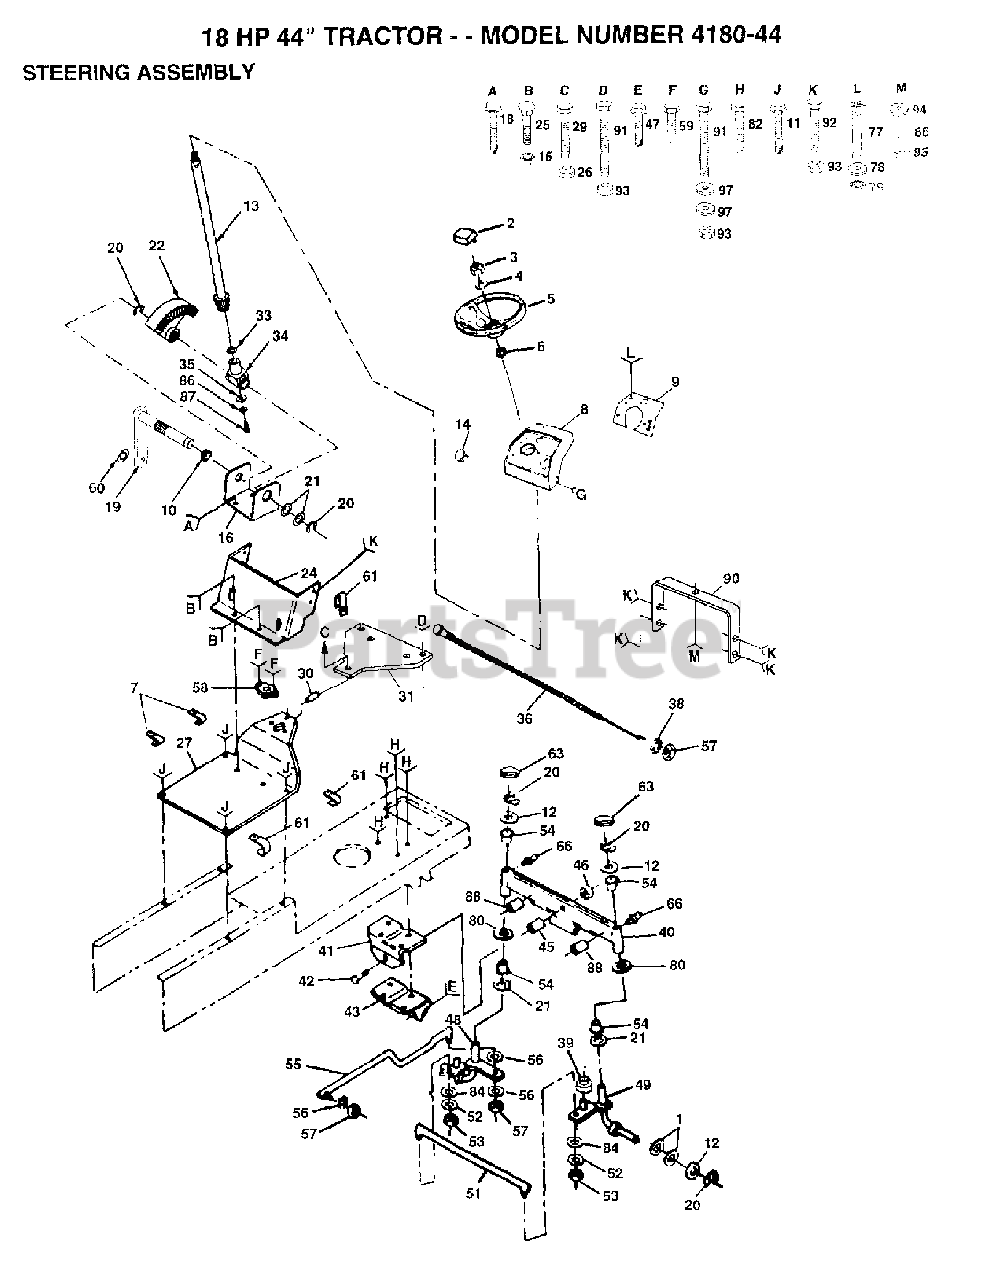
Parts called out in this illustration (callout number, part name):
2	INSERT STR WHL
3	NUT.HEX.1/2-20
5	Steering Wheel
7	CLIP,INSULATOR
10	NYLINER T (7283A)
14	PLUG-DASH T
16	BRKT,STEERING
19	SHAFT,PITMAN
20	RING CLIP
21	WASHER THRUST
22	GEAR.SECTOR
24	DASH LOWER YT NLA
26	NUT.71038.31-18.HEX.NYLOCK
31	PLATE, BATTERY
33	THRUST WASHER
34	SHAFT,SUPPORT
35	WASHER
36	CONTROL CHOKE
38	LOCKWASHER
39	Poulan TBD
40	AXLE ASSY
41	SUPPORT-SADDLE LT NLA
43	SUP-SADDLE FRT LT
46	LOCK NUT
47	SCREW LT
52	LOCKWASHER
53	LOCKNUT
54	BEARING.STEERING.COLUMN
55	DRAG LINK
56	WASHER, LOCK 3/8
57	NUT
58	BUSHING
59	SCREW LT
60	WASHER
61	CLIP T
63	CAP.SPINDLE.BLACK
66	ZERK.GREASE.TAPERED
78	WASHER
84	WASHER M
86	LOCKWASHER
90	SUPPORT ASS'Y
93	NUT
94	WASHER PM
95	NUT
97	WASHER
